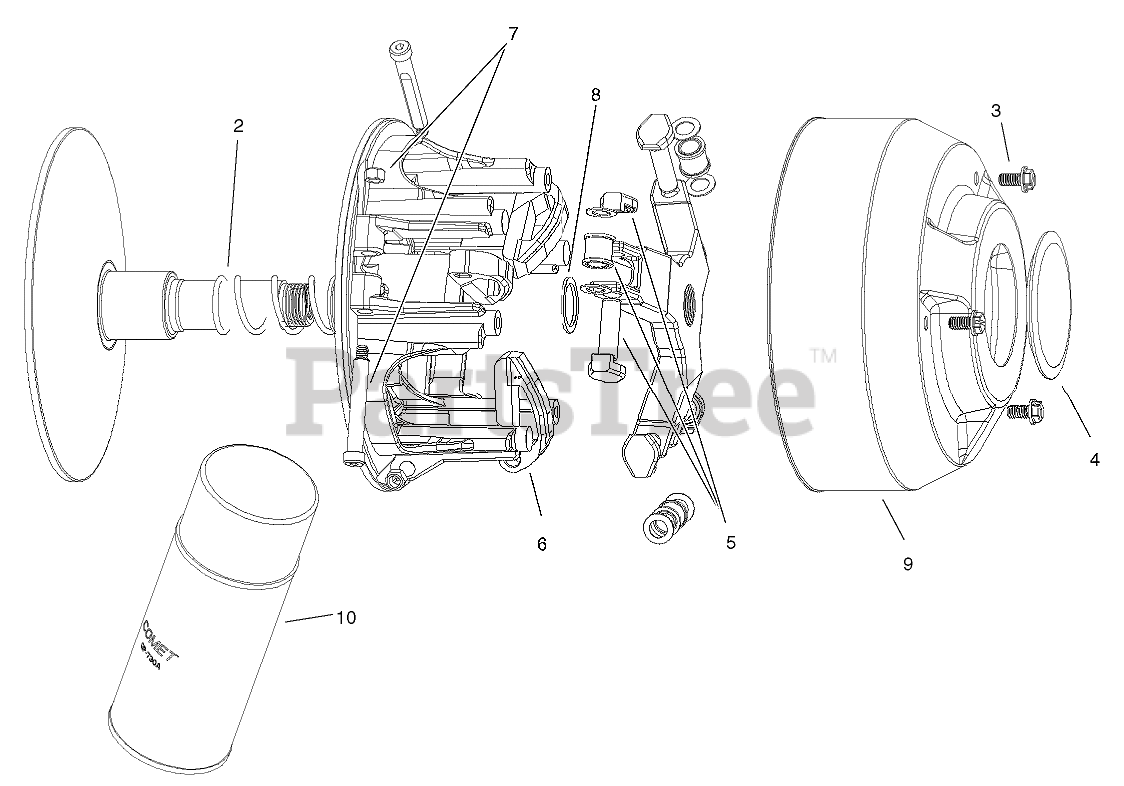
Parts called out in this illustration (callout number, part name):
2	SPRING
3	SCREW-HHF
5	SPIDER ROLLER KIT
6	CAM ARM
7	BUTTON KIT
8	SPACER
9	COVER
10	LUBRICANT-DRY
